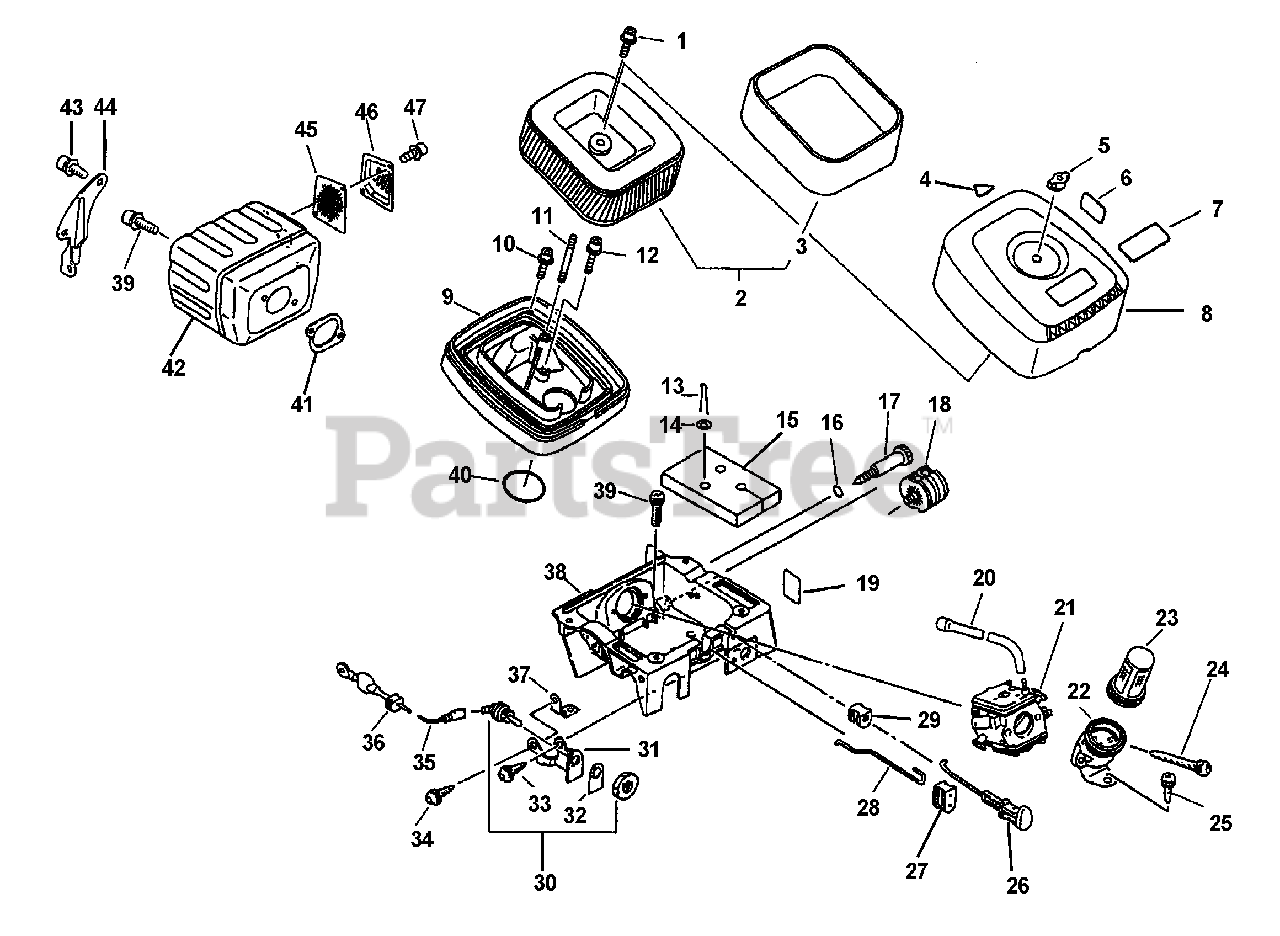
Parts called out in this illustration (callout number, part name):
1	SCREW - 5X16
2	FILTER, AIR
3	FILTER, AIR
5	NUT
6	LABEL - CAUTION
7	LABEL - MODEL
8	COVER, AIR FILTER
9	CASE, AIR FILTER
10	SCREW - 5X16
12	SCREW - 5X25
13	PIN, SPLIT - 3X18
15	PAD, FOAM
16	O-RING - 7
17	SCREW, IDLE ADJUST
19	LABEL - IDLE
20	PIPE - IMPULSE
21	CARBURETOR HDA-166A
22	MOUNT, AIR FILTER
23	SCREEN, DEBRIS
24	SCREW - 5X55
25	SCREW - 5X14
26	ROD, CHOKE
27	GUIDE, THROTTLE ROD
28	ROD, THROTTLE
29	GROMMET
30	IGNITION SWITCH ASSY
31	BRACKET, SWITCH
32	LABEL - SWITCH
33	SCREW - 5X10
34	SCREW - 4X10
35	LEAD - GROUND
37	TERMINAL - GROUND
38	CASE, CARBURETOR
39	SCREW - 5X20
40	O-RING - 29
41	GASKET, EXHAUST
42	MUFFLER
43	SCREW - 5X14
44	BRACKET, MUFFLER
45	SCREEN, SPARK ARRESTOR
46	GUIDE, EXHAUST
47	SCREW - 4X10
